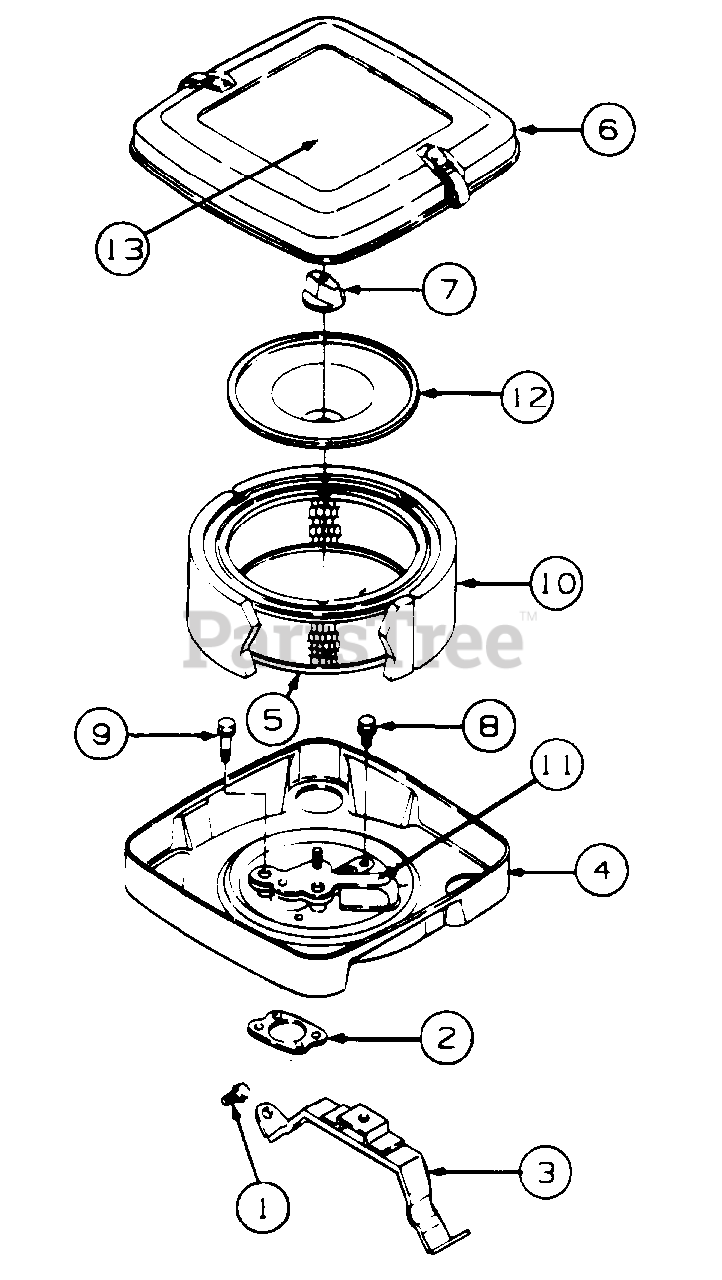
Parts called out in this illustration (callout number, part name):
1	Screw, Sems
2	Gasket, Air Cleaner
3	Bracket, Air Cleaner
4	Base, Air Cleaner
5	Cartridge, Air Cleaner
6	Cover, Air Cleaner
7	Knob, Air Cleaner
8	Screw, Sems
9	Screw, Sems
10	Element, Foam
11	Shield Assy
12	Plate, Air Cleaner
13	Label, V-Twin Engine
